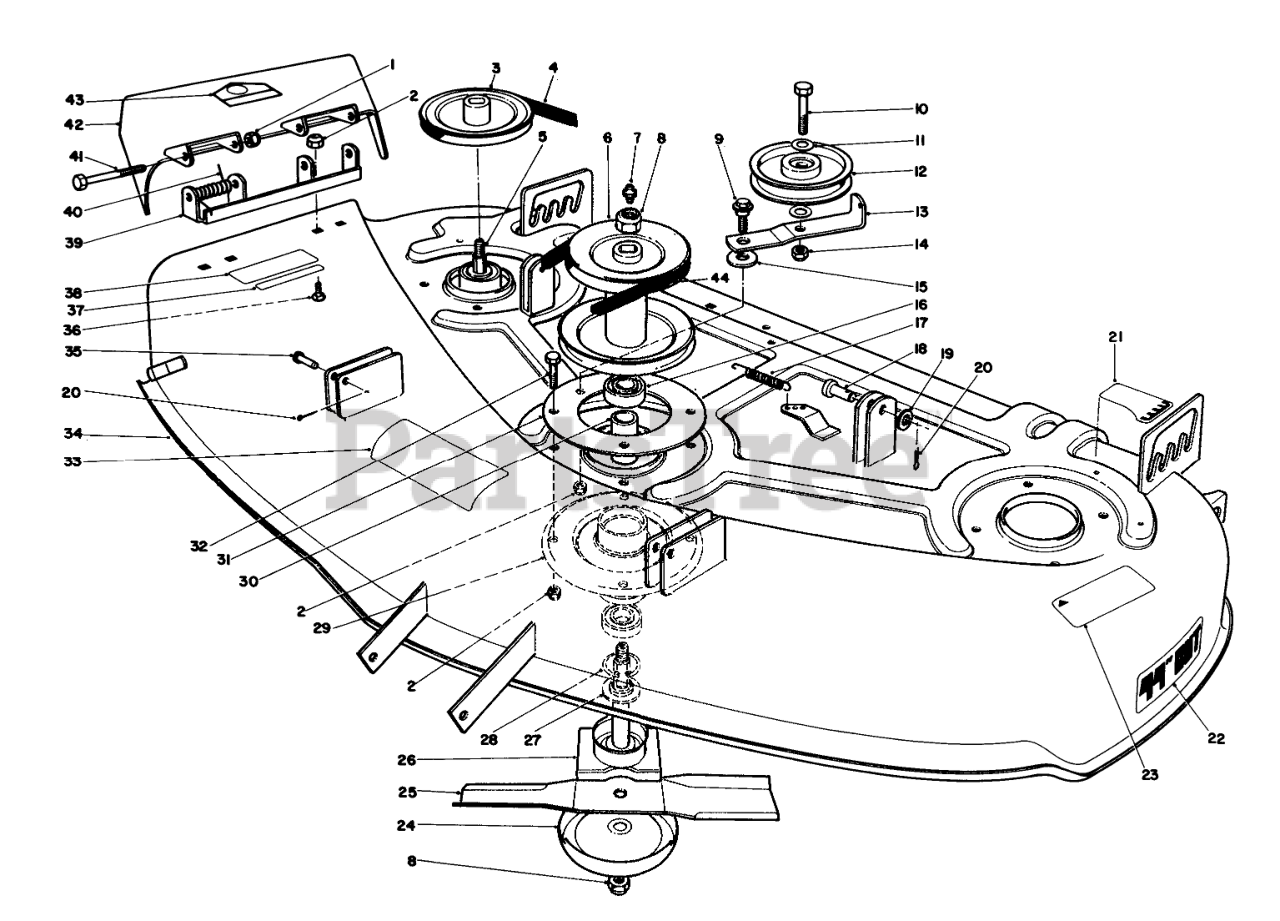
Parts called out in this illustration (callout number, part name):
1	NUT-HEX
2	NUT-LOCK, NI
3	DECK PULLEY
4	V-BELT, ENG/DECK
5	SPDL/BLD RET.WA
6	PULLEY WA B
7	FITTING-GREASE
8	NUT-LOCK NI
9	SCREW-SHOULDER
10	SCREW-HH
11	WASHER-FLAT
12	PULLEY-IDLER
13	DECK DR IDLER ARM B
14	NUT-LOCK, NI
15	WASHER-PIVOT
16	BEARING-BALL
17	SPRING-EXTENSION
18	PIN-CLEVIS
19	WASHER-FLAT
20	PIN-COTTER
21	Decal
22	44" DECK DECAL
23	DECAL-CAUTION, BLADE
24	Cup
25	Blade
26	SPDL/BLD RET.WA
27	SPACER-SPINDLE
28	RING-RETAINING
29	Spindle
30	BEARING SPACER
31	DECK RING
32	SCREW-HH
33	BELT ROUTING DECAL
34	44" DECK WA B
35	PIN-CLEVIS
36	SCREW-CARR
37	DECAL-NO STEP
38	DECAL-CAUTION, DEFLECTOR
39	PIVOT BRKT WA R/B
40	SPRING
41	SCREW-HH
42	DEFLECTOR/DECAL ASM (44")(BLACK)
43	DECAL-DANGER
44	V-BELT
